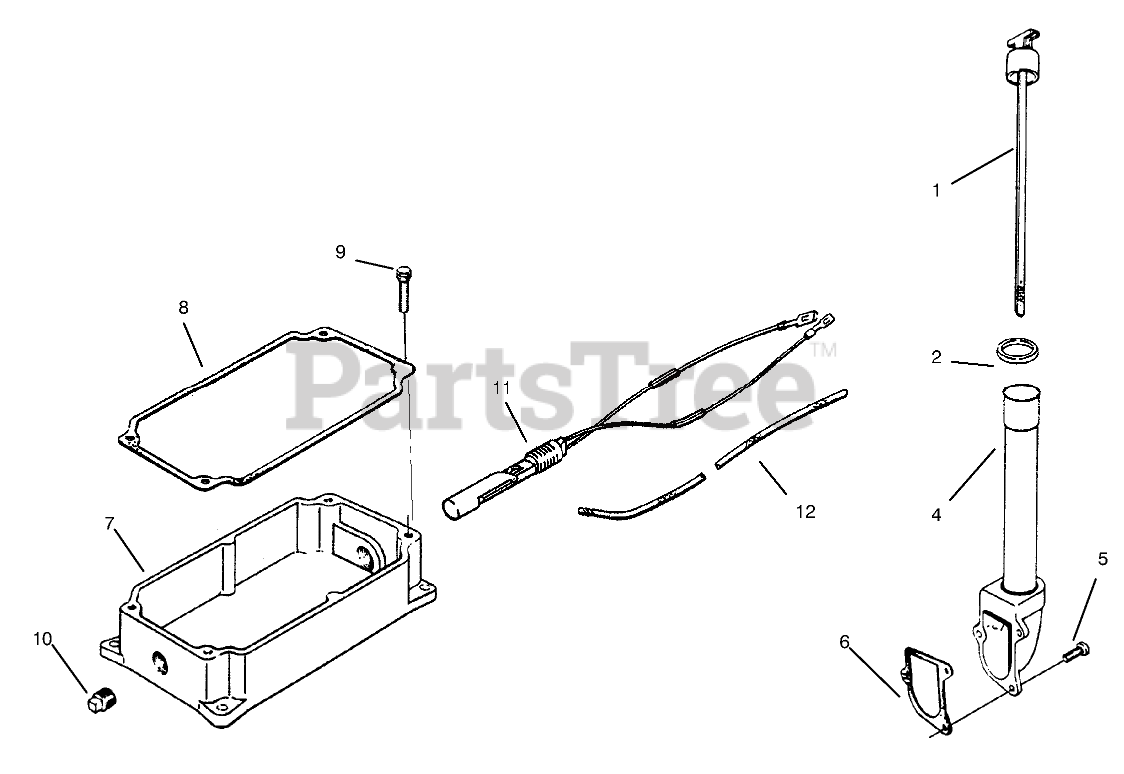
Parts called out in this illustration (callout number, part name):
1	Dipstick
4	Adapter-Oil Fill
5	Screw
6	Gasket
7	Pan-Oil
8	Gasket
9	Screw
10	Plug
11	Kit-Float Switch
